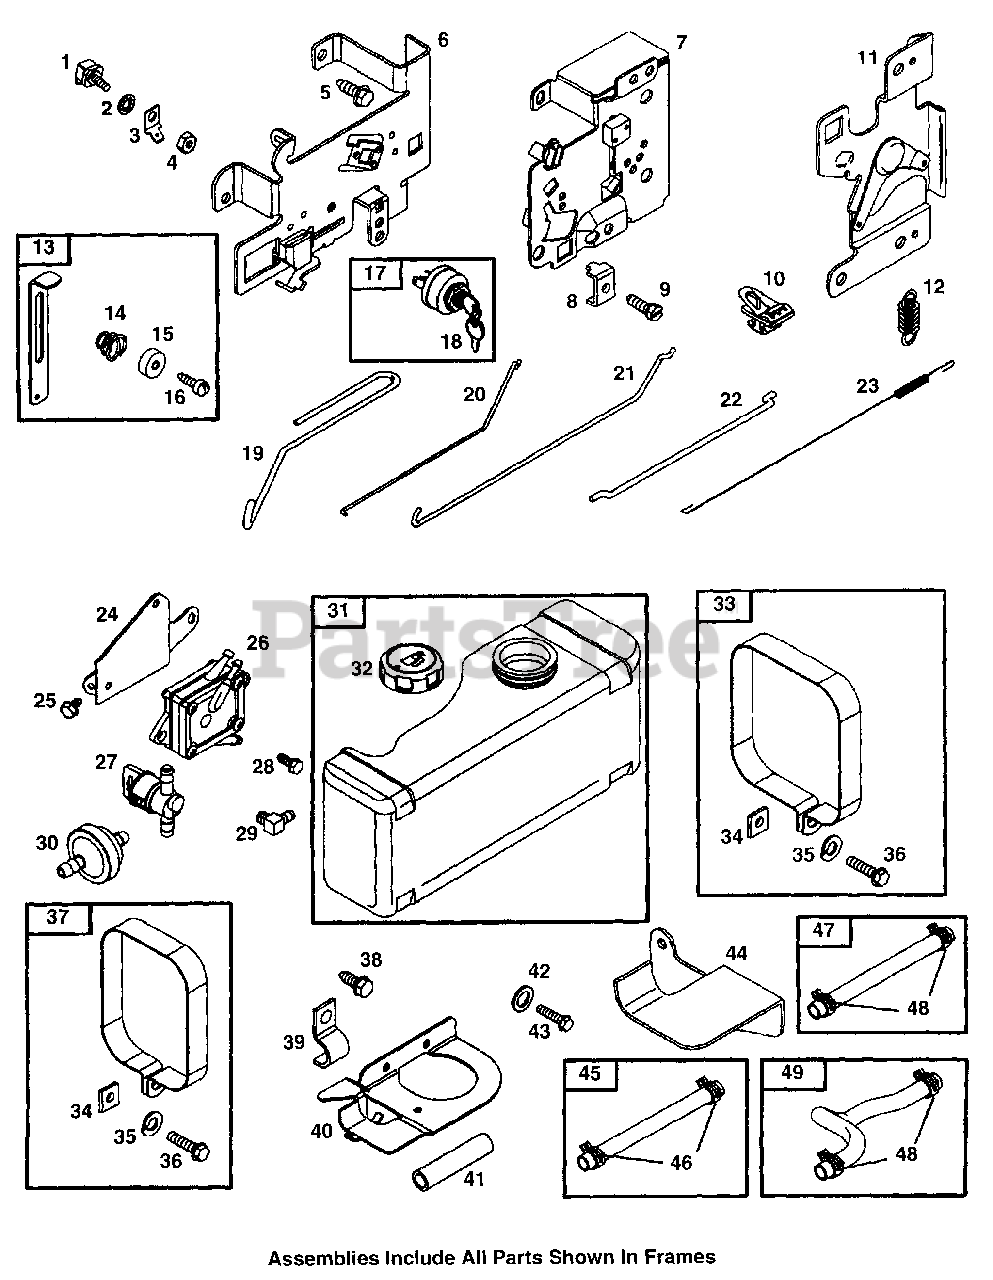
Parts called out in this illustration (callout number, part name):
1	Insulated Terminal
2	Internal Lockwasher
3	Spade Terminal
5	Tapping Hex Screw
6	Control Assy Plate (Choke A Matic)
7	Governor Control Plate
8	Casing Clamp
9	Sem Hex Head Screw, 10-32 x 58
10	Stop Assy Switch
11	Governor Lever
12	Governor Spring
13	Friction Control Slide
14	Friction Spring
15	Friction Spring
16	Machine Fill Screw, 10-32 x 5/8
17	Ignition Switch w/Keys
19	Choke Link
20	Choke Link
21	Mechanical Governor Link
22	Bell Crank Link (Governor)
23	Link Spring
24	Pump Bracket
25	Tapping Hex Screw, 8-32 x 3/8
26	Impulse Pump
27	Shut Off Valve
28	Machine Hex Screw, 1/2" Long
29	Fuel Connector
30	Fuel Filter
32	Tank Cap
33	Tank Strap, RH
34	Square Nut, 1/4-20
35	Lock Washer
36	Hex Screw
37	Tank Strap, LH
38	Hex Washer Head Screw
39	Breather Tube Clamp
40	Tank Bracket (P-29)
41	Heat Deflector
42	Flat Washer
43	Sem Hex Head Screw
44	Tank Bracket, RH
45	Vacuum Hose, 11"
46	Hose Clamp, Black
47	Fuel Assy Hose, 6 3/4"
48	Hose Clamp, Green
49	Fuel Assy Hose
